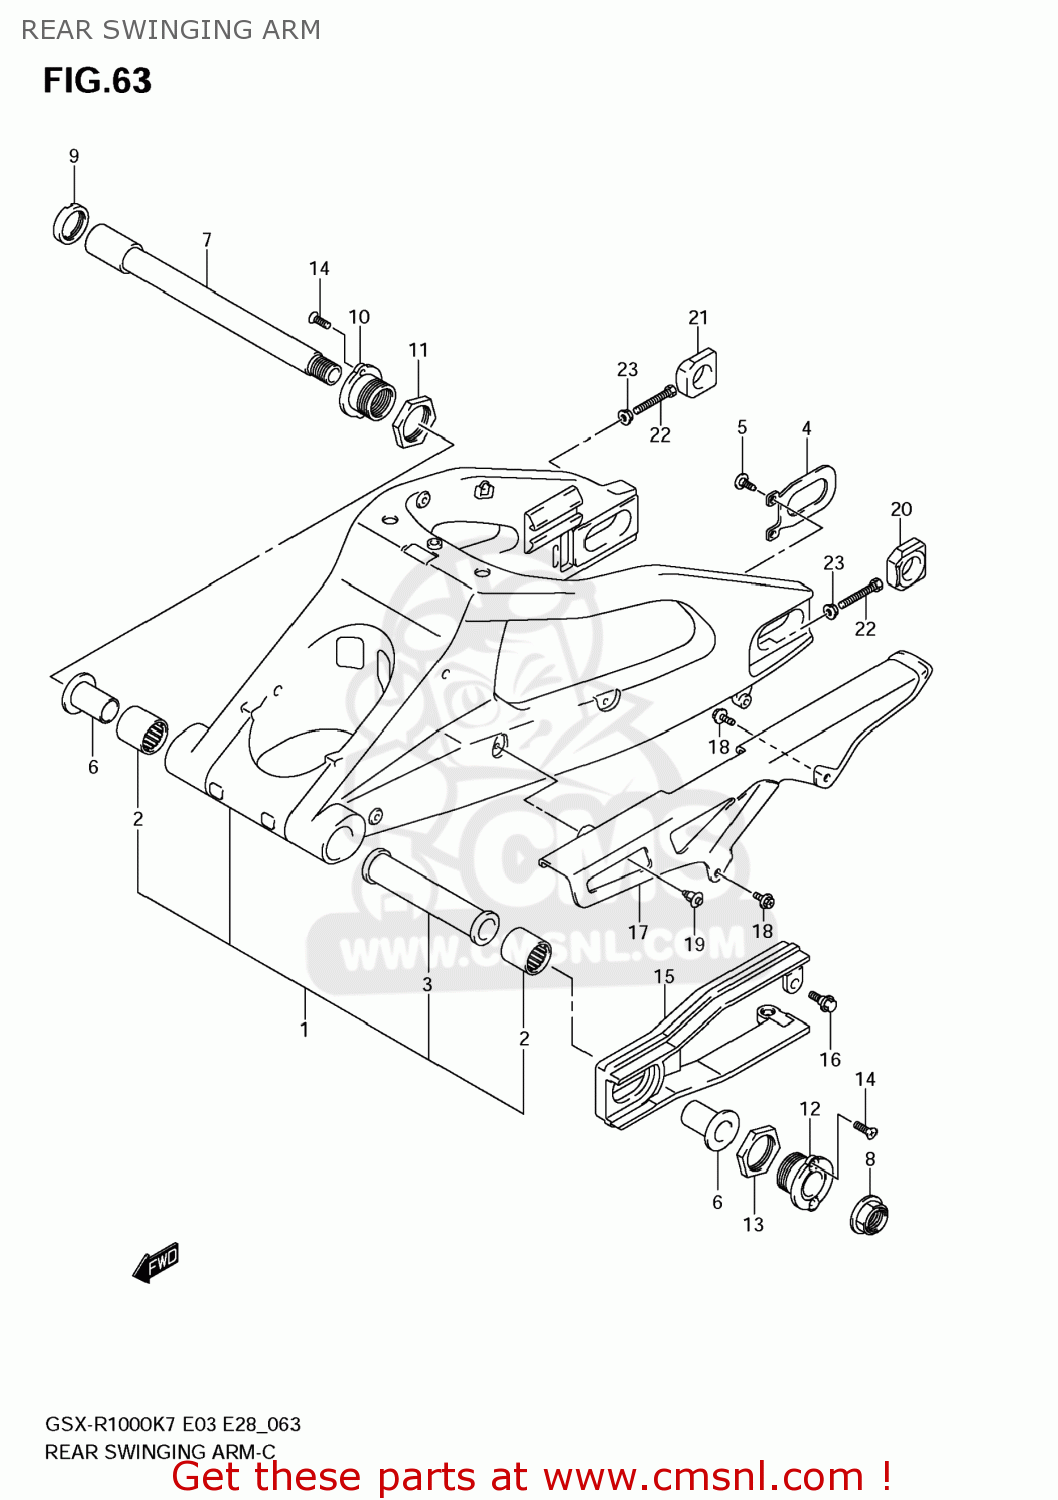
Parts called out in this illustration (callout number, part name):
1	SWINGINGARM ASSY,RR
2	BEARING(27X35X35)
3	SPACER,RR SWG PVT CTR
4	PLATE,RR SWING ARM BRKT
5	SCREW(6X16)
6	SPACER,RR SWGARM PIVOT BEARING
7	SHAFT,RR SWINGINGARM PIVOT
8	NUT
9	NUT,REAR SWGAR
10	BOSS,RR SWINGINGARM PIVOT,R
11	NUT,RR SWGARM PIVOT BOSS,R
12	BOSS,RR SWINGINGARM PIVOT,L
13	NUT,RR SWGARM PIVOT BOSS,L
14	SCREW
15	BUFFER,CHAIN TOUCH DEFENSE
16	BOLT(6X17.8)
17	CASE,CHAIN
18	BOLT
19	CLIP(BLACK)
20	ADJUSTER,CHAIN
21	ADJUSTER,CHAIN
22	BOLT(8X60)
23	NUT
